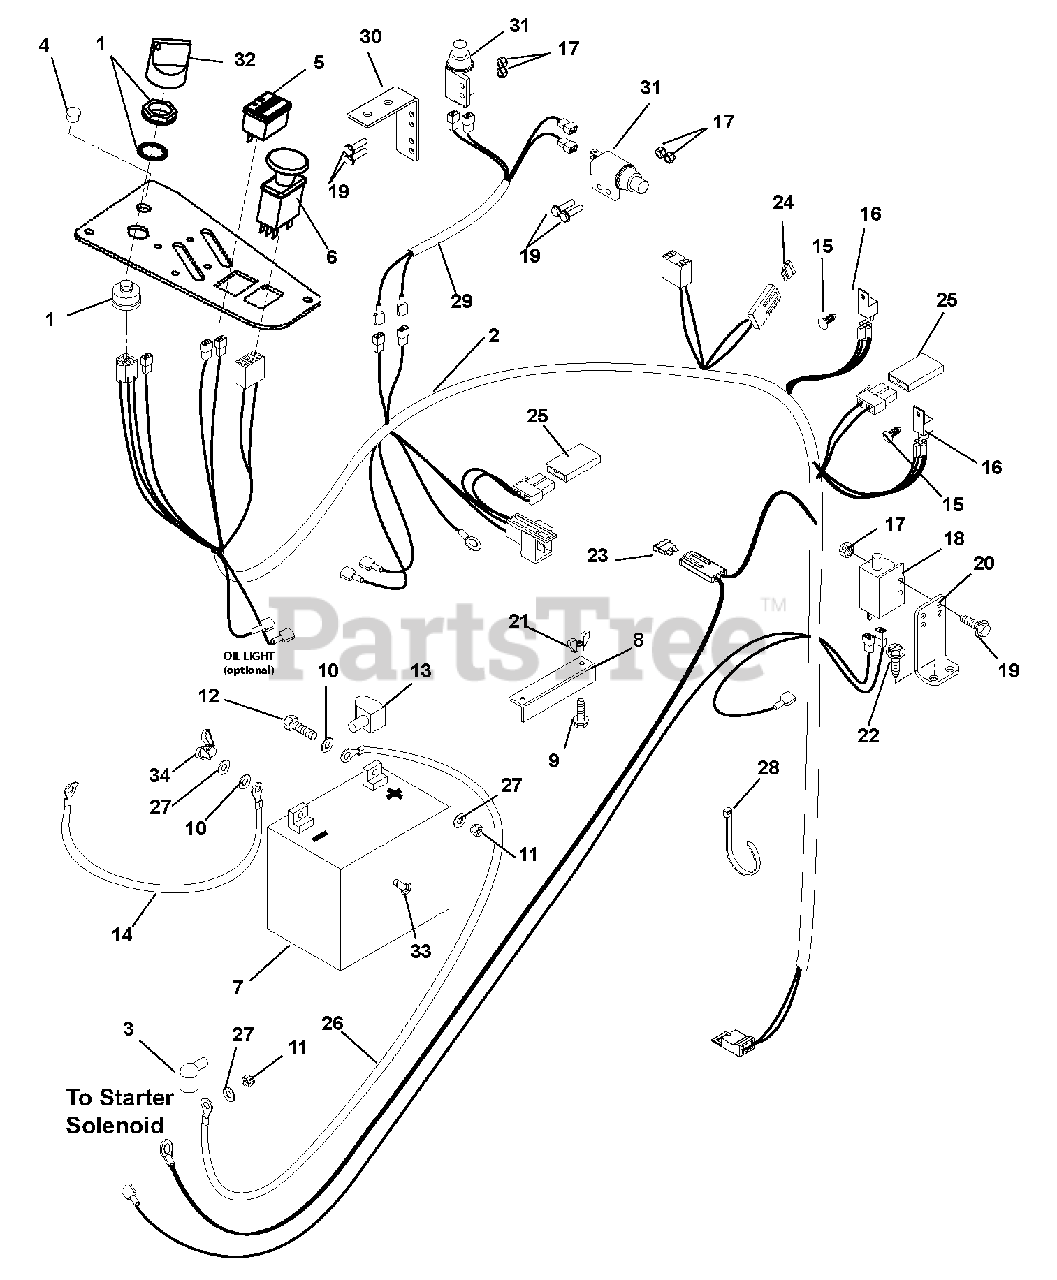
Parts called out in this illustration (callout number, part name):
1	Key Switch Assy (Includes key)
2	Harness, CZ Remote Solenoid
3	Boot, Eyelet Terminal
4	Plug, Hole .50 Diameter
5	Hour Meter – with Maintenance
6	Switch, Clutch with Retainer Ring
8	Hold Down
9	Bolt, Round Head Square Neck .25-20 x 7.50
10	Washer, Flat Steel .281 x .620 x .065
11	Nut, Hex .25-20
12	Bolt, Hex .25-20 x .75 Grade 5
13	Insulator
14	Cable, Negative Battery
15	Rivet, .25 Nylon Panel
16	Relay (Included with Harness)
17	Nut, Locking Nylon 10-24 with Insert
18	Switch, Single Pole
19	Screw, Machine 10-24 x .75 Hex Washer Head
20	Mount, Brake Switch
21	Nut, Locking Wing .25-20
22	Screw, Tapping .25-20 x .50 Hex Washer Head
23	Fuse, 25 Amp (Included with Harness)
24	Fuse, 20 Amp
25	Diode, Connector Shell
26	Cable, Starter
27	Washer, Lock .25 x .062
28	Tie, Cable LG 5.50
29	Harness, CE Foot and Seat Plate Switch
30	Mount, Switch
31	Switch, Single Pole (N.O.) with Cover
32	Key, with Shield
33	Bolt, Round Head Square Neck .25-20 x .75 G5 YZ
34	Nut, Wing .25-20 YZ
